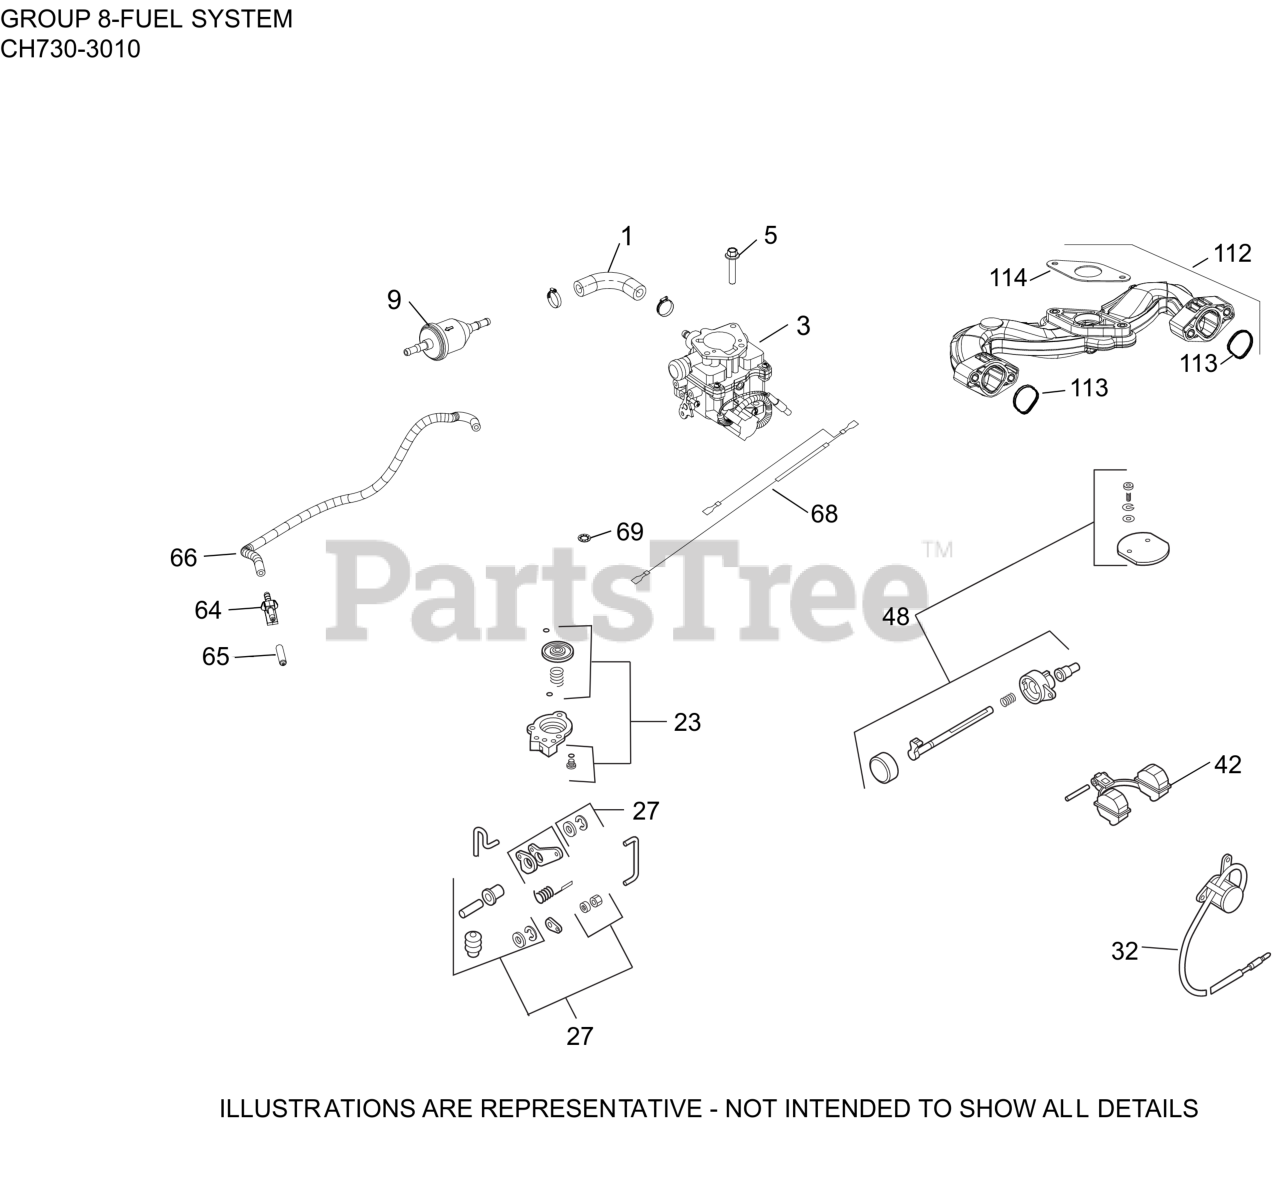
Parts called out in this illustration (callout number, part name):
1	HOSE,LW PERM.FUEL 24.00"-USE 25 111 81-S
3	KIT, CARBURETOR COMPLETE
5	SCREW, FLG M6X1.0X25
9	FILTER, FUEL
23	KIT, REPAIR ACC PUMP
27	KIT, REPAIR-ACC PUMP SEAL
32	KIT, SOLENOID
42	KIT, REPAIR FLOAT
48	KIT, REPAIR CHOKE
64	CONNECTOR, EVAPORATIVE
65	CAP, MASKING
66	HOSE, EVAPORATIVE 20"- (#24326143S)
68	LEAD, GROUND
69	WASHER, INT TOOTH LOCK 1/4"
112	INTAKE MANIFOLD W/GASKETS
113	O-RING, INTAKE PORT
114	GASKET, CARBURETOR (PIM, CH)
NI	KIT, HIGH ALT (8,000+ FT)
NI	KIT, HIGH ALT (4000-8000 FT)
NI	KIT, REPAIR CARBURETOR
